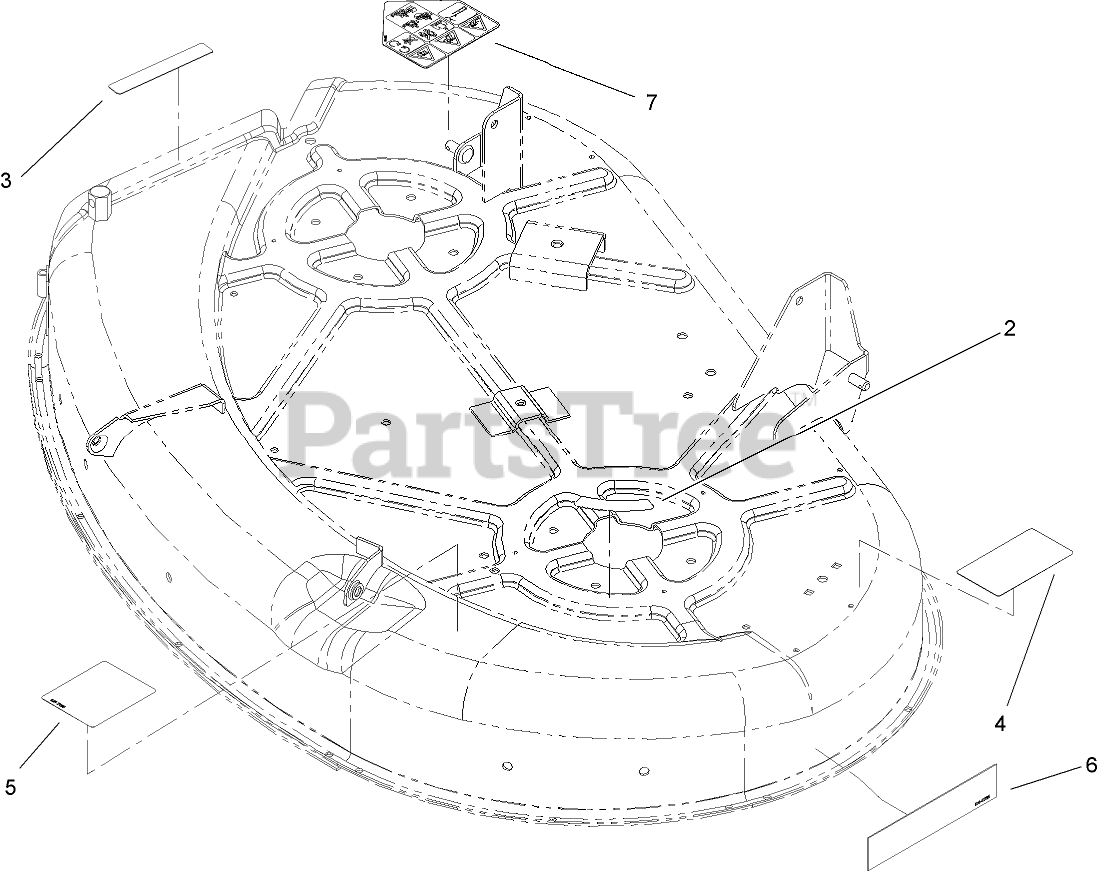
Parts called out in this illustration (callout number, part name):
2	DECAL-DANGER, SHIELD
3	DECAL-DANGER
4	DECAL-DANGER
5	DECAL-ROUTING, BELT
7	DECAL-DANGER, SHIELD
